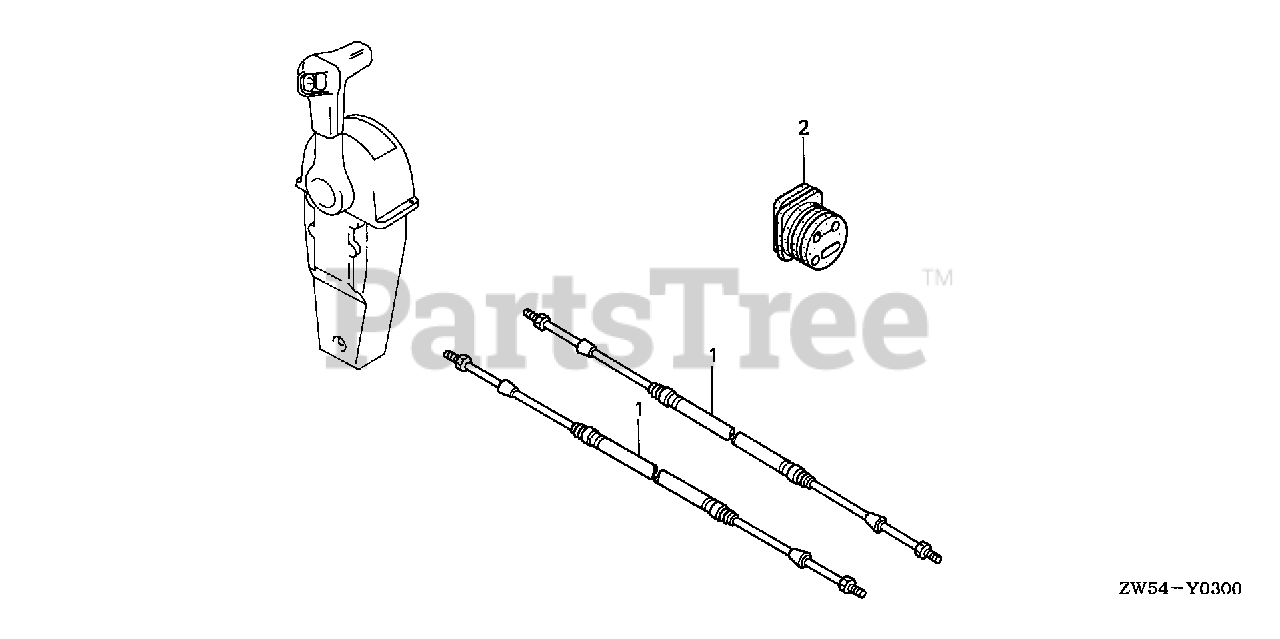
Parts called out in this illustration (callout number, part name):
1	CABLE ASSY., PUSH-PULL
1	CABLE, REMOTE CONTROL (10')
1	CABLE, REMOTE CONTROL (11')
1	CABLE, REMOTE CONTROL (12')
1	CABLE, REMOTE CONTROL (13')
1	CABLE, REMOTE CONTROL (14')
1	CABLE, REMOTE CONTROL (15')
1	CABLE, REMOTE CONTROL (16')
1	CABLE, REMOTE CONTROL (17')
1	CABLE, REMOTE CONTROL (18')
1	CABLE, REMOTE CONTROL (19')
1	CABLE, REMOTE CONTROL (20')
1	CABLE, REMOTE CONTROL (21')
1	CABLE, REMOTE CONTROL (22')
1	CABLE, REMOTE CONTROL (23')
1	CABLE, REMOTE CONTROL (24')
1	CABLE, REMOTE CONTROL (25')
1	CABLE, REMOTE CONTROL (26')
1	CABLE, REMOTE CONTROL (27')
1	CABLE, REMOTE CONTROL (28')
1	CABLE, REMOTE CONTROL (29')
1	CABLE, REMOTE CONTROL (30')
1	CABLE, REMOTE CONTROL (31')
1	CABLE, REMOTE CONTROL (32')
1	CABLE, REMOTE CONTROL (33')
1	CABLE, REMOTE CONTROL (34')
1	CABLE, REMOTE CONTROL (35')
2	GROMMET, CASE (LOWER) (B)
